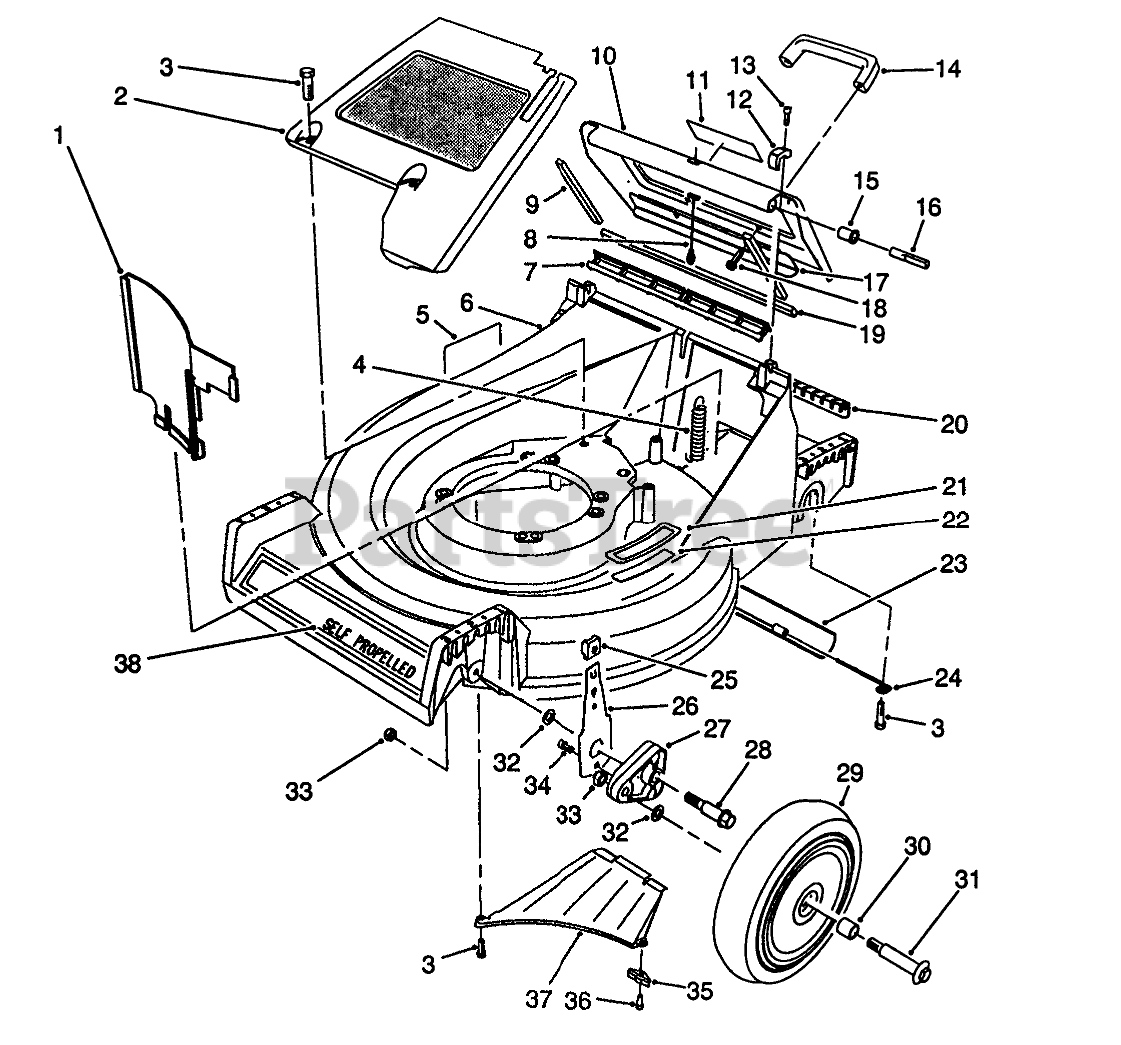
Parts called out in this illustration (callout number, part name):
1	PANEL-VERTICAL
2	PaneI-Screen
3	SCREW-HWHTF
4	EXTENSION-SPRING
5	DECAL-DANGER
6	Housing-21 " (Incl. Ref. #5, 21 & 22) (Model No. 26624)
7	DOOR SEAL
8	DOOR CABLE
9	DOOR SIDE SEAL
10	Door-Discharge (Incl. Ref. #9, 11, 17 & 19) (Model No. 26624)
11	DECAL - WARNING
12	HINGE CLAMP
13	SCREW-HSH
14	HANDLE-DOOR
15	DOOR BUSHING
16	HINGE PIN
17	DOOR - BRACE
18	SCREW-HWH
19	DOOR END SEAL
20	ACCESS COVER
21	STEP PAD
22	STEP PAD DECAL
23	TRAILING SHIELD
24	LH SHIELD HANGER
25	KNOB-ARM
26	FRONT SPRING ARM ASM
27	ARM-PIVOT, FRONT
28	BOLT-SHOULDER
29	Wheel & Tire Assembly (Incl. Ref. #30)
30	BUSHING
31	WHEEL BOLT
32	WASHER
33	Nut
34	SCREW-HSH, THREAD FORMING
35	Bracket-Discharge
36	SCREW-HWHTF
37	Ramp Discharge
38	DECAL - DECK
